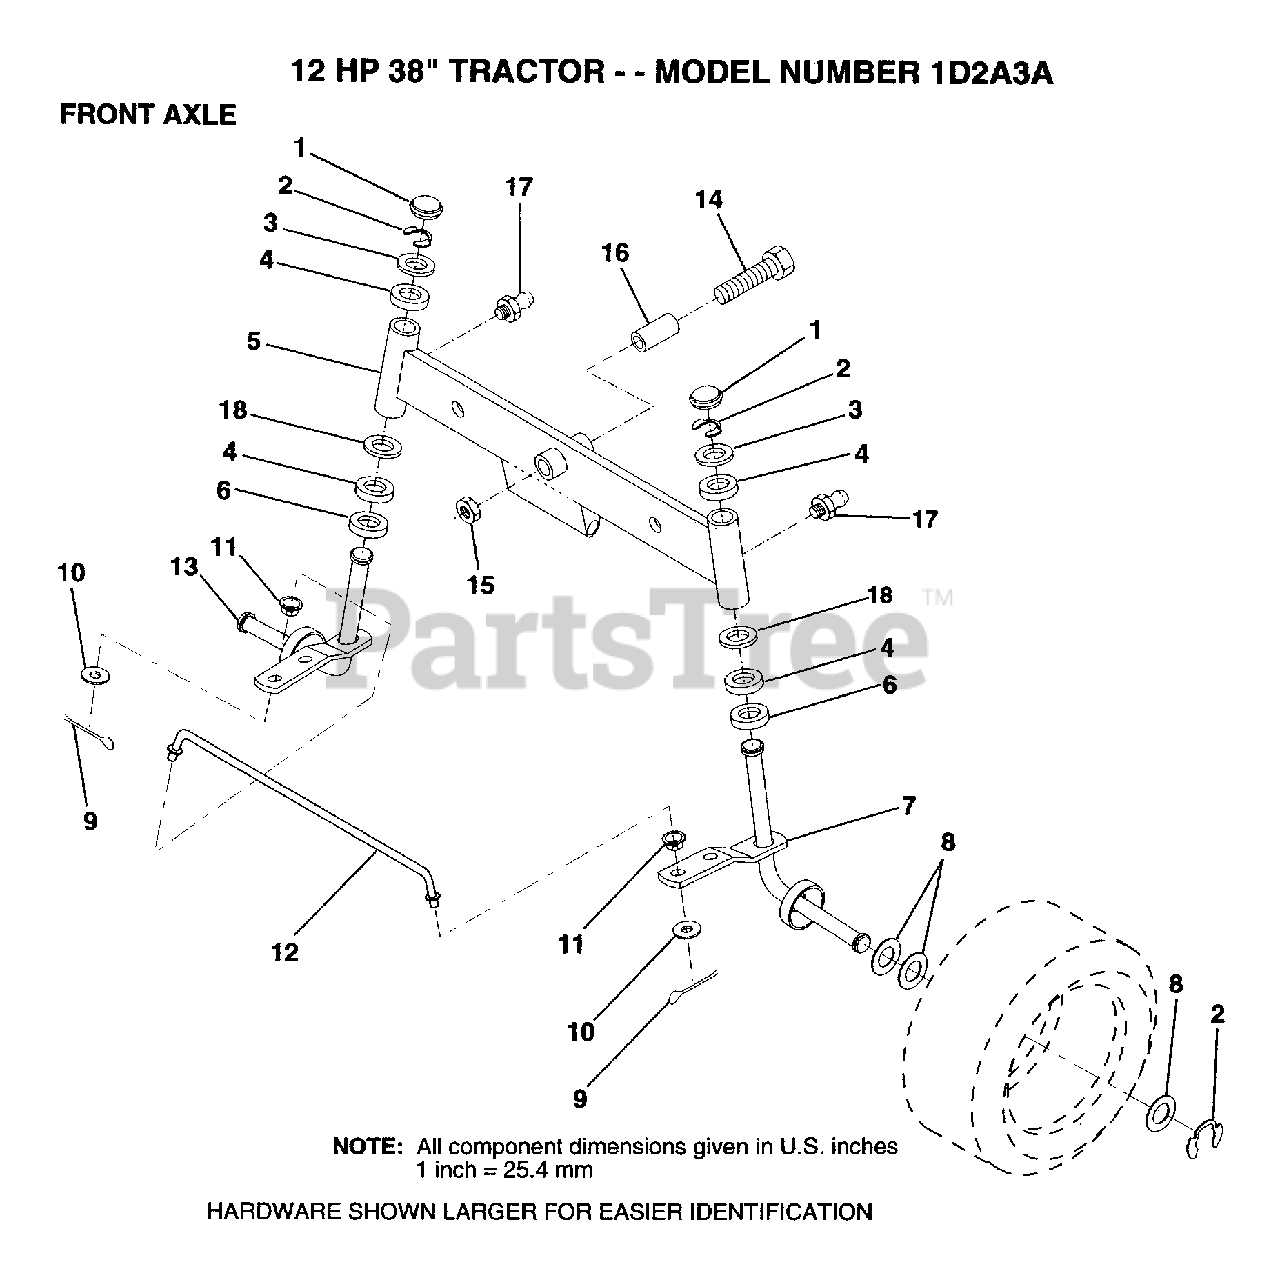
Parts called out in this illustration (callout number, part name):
1	CAP
2	RING
3	WASHER
4	COL. SRTG. BEAR.
6	WASHER .T
7	SPINDLE ASM RH
8	WASHER
9	COTTER PIN
10	WASHER
11	BUSHING.DRAGLINK
12	TIE ROD
13	SPINDLE ASM LH
14	BOLT HEX 5/8-11
15	"NUT-LOC,FLANGE LT"
16	BEARING
17	ZERK M
18	WASHER
